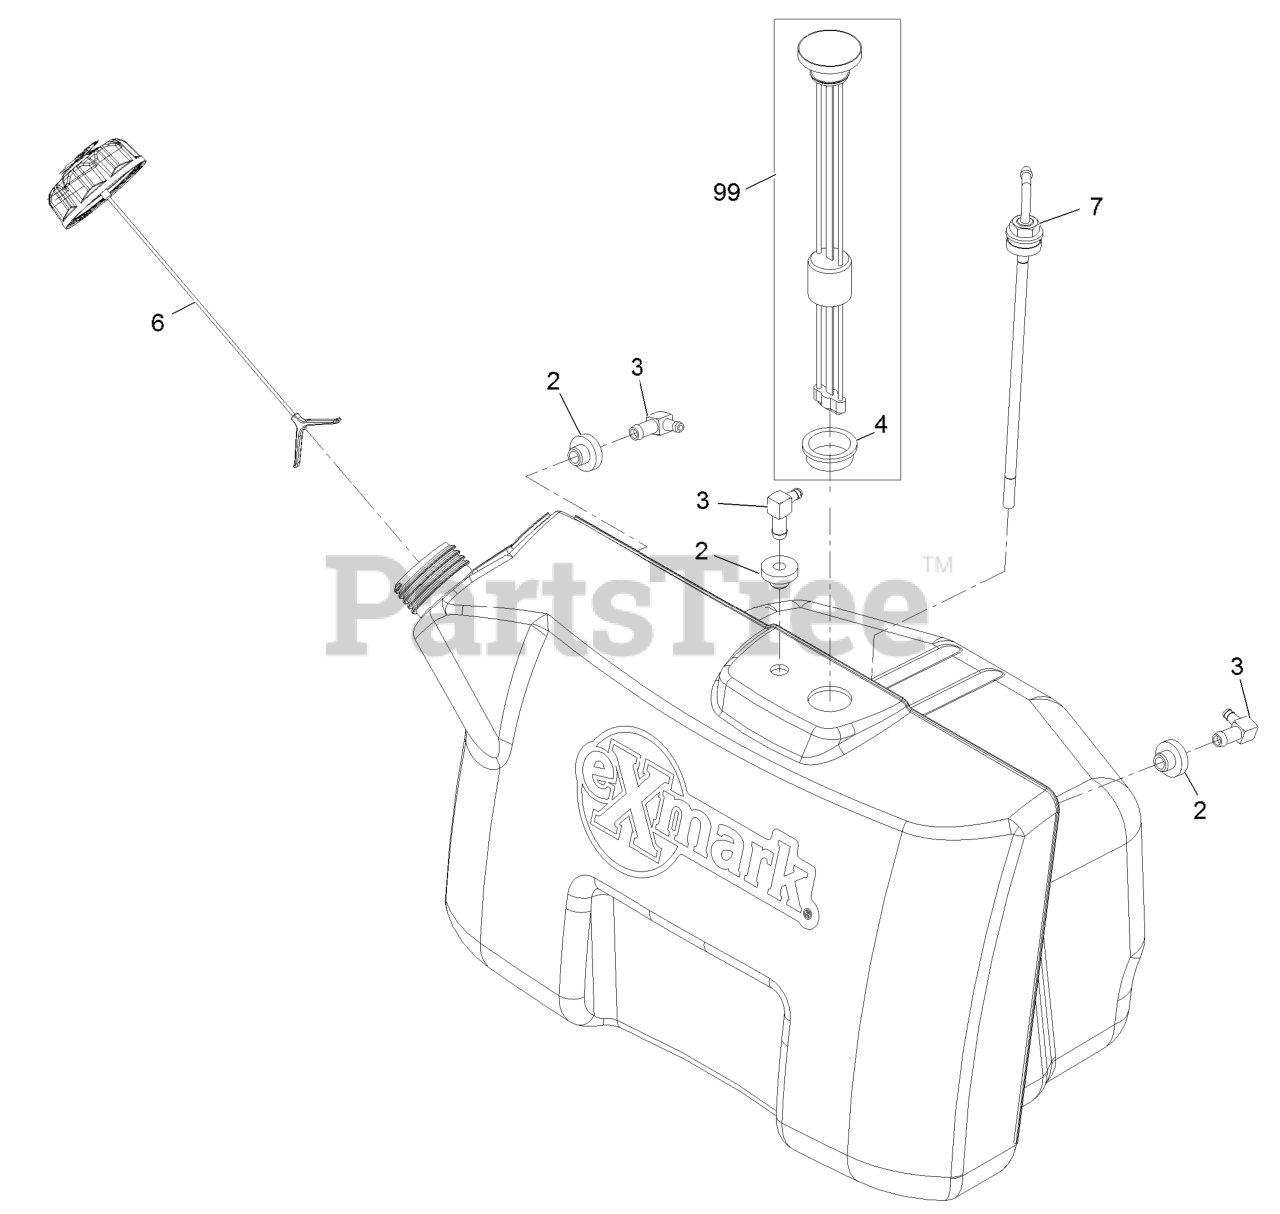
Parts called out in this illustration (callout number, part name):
2	BUSHING
3	ELBOW-90 DEG
4	CONTACT ORDER SERVICES
7	FITTING-FUEL, BULKHEAD
99	KIT, VANTAGE FUEL GAGE RE
